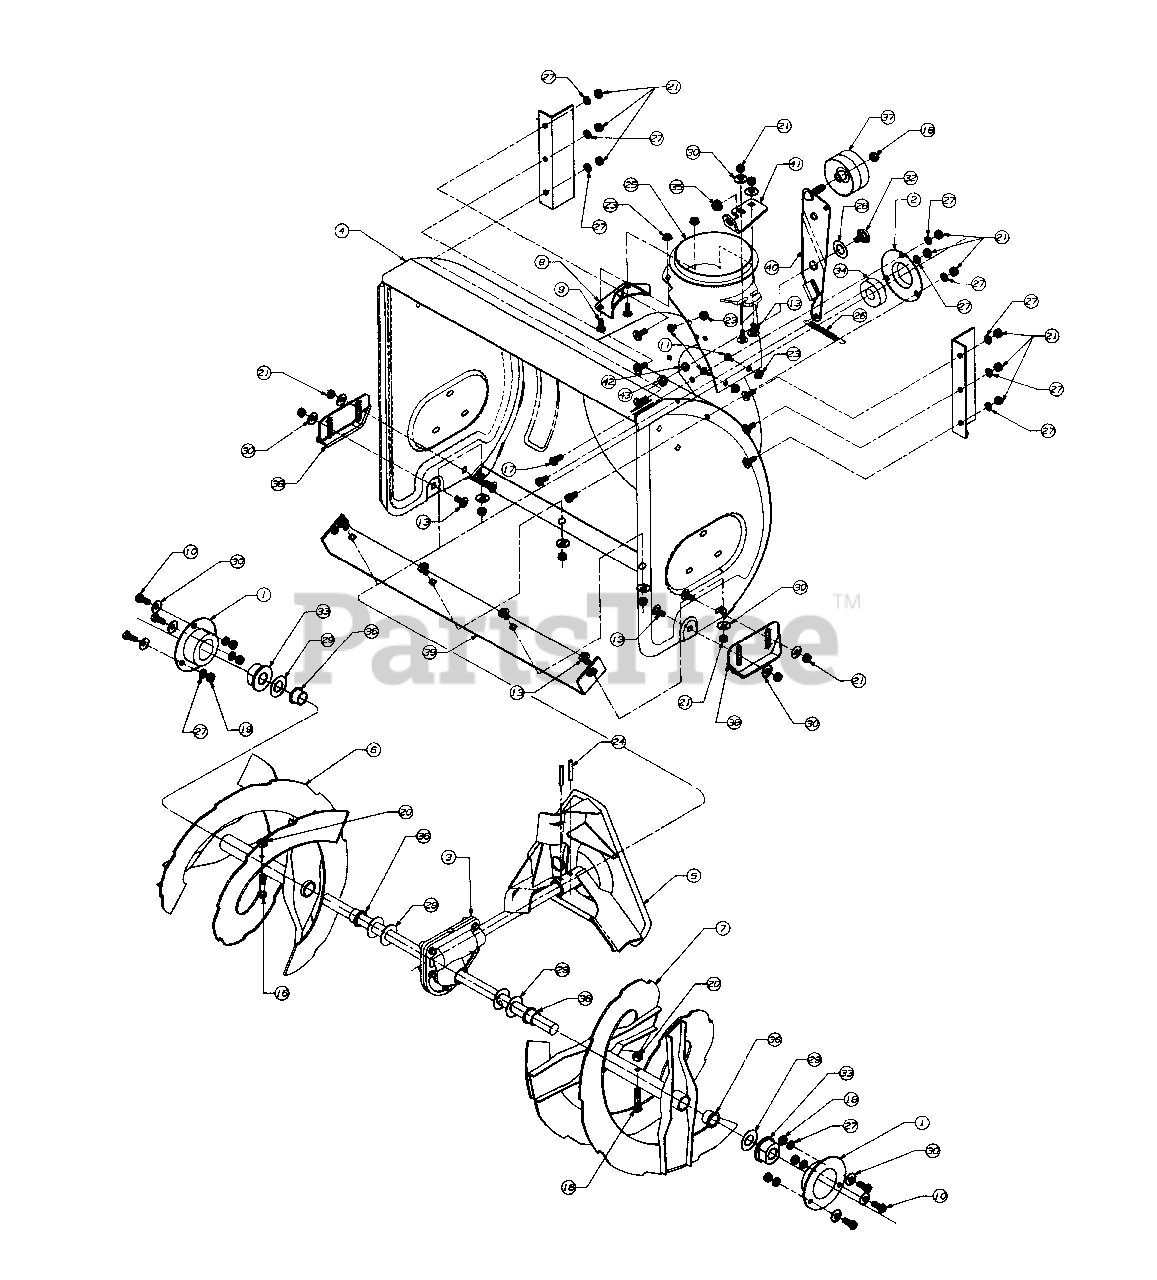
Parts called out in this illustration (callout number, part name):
2	Housing, Bearing
3	Gear Assembly (22")
9	Bolt, Carriage
10	Screw, Hex
11	Screw, Carriage
13	Screw, Carriage
16	Bolt, Shear
18	Hex Lock Nut
20	Nut, Hex Lock
21	Nut, Hex
23	Nut, Lock, Hex, Flanged
24	Spring Pin
25	Adapter, Chute
26	Spring
27	Lock Washer
28	Washer, Flat
29	Washer, Flat, .76 I.D. x 1.49 O.D. x .06
30	Washer, Bell
32	Screw, Shoulder
33	Bearing, Flange
34	Bearing, Ball
35	Bushing, Plastic
36	Bushing, Flange
37	Idler, Flat
40	Arm, Auger Idler
42	Lock Washer
43	Hex Nut
